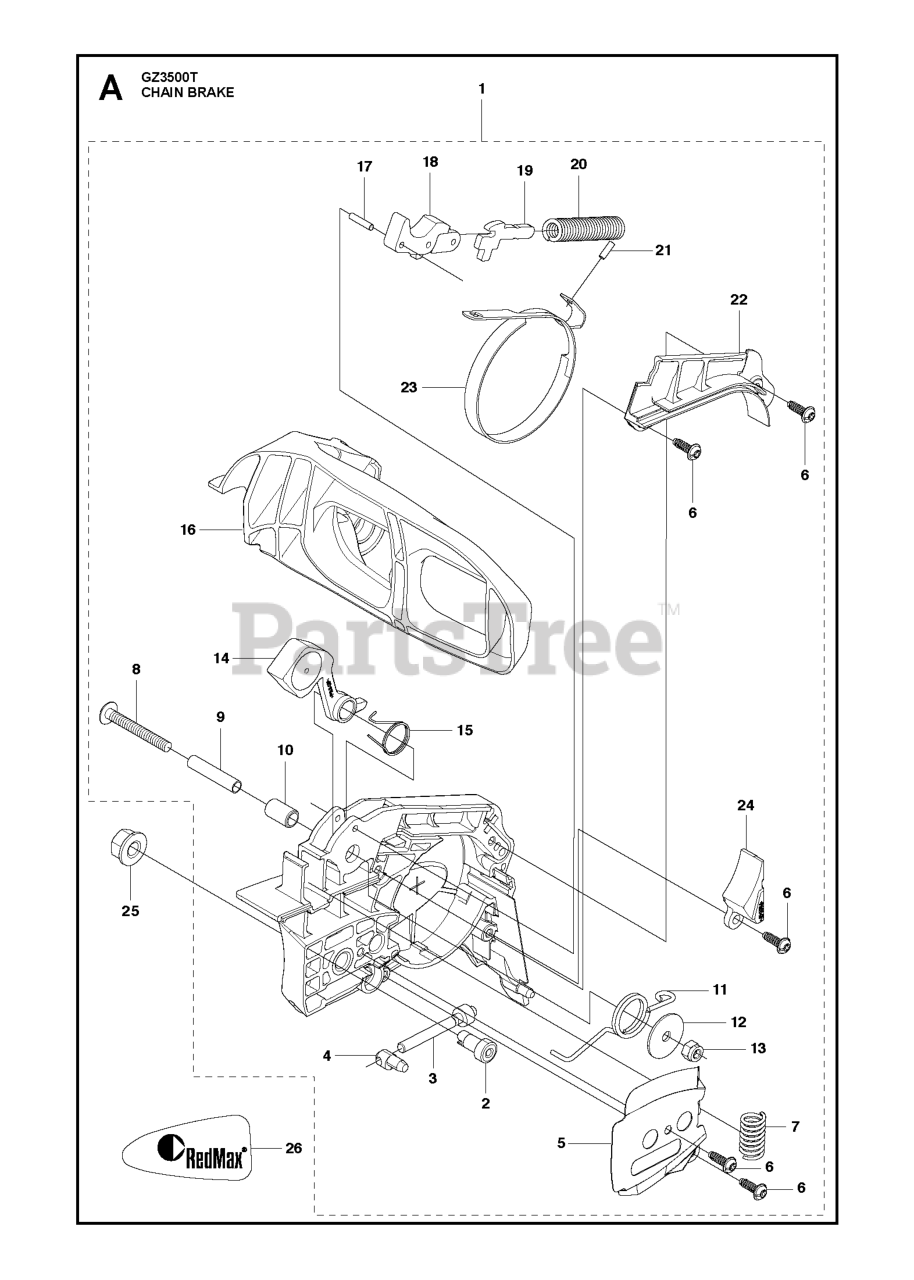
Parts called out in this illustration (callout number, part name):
3	SCREW
6	SCREW
8	SCREW
9	SPACER INNER
10	SPACER
11	RETURN SPRING
12	WASHER
15	SPRING
17	ROLLER
18	BRAKE LEVER
19	ARM
20	SPRING
21	ROLLER
23	BRAKE BAND
25	NUT M8 FLANGE
